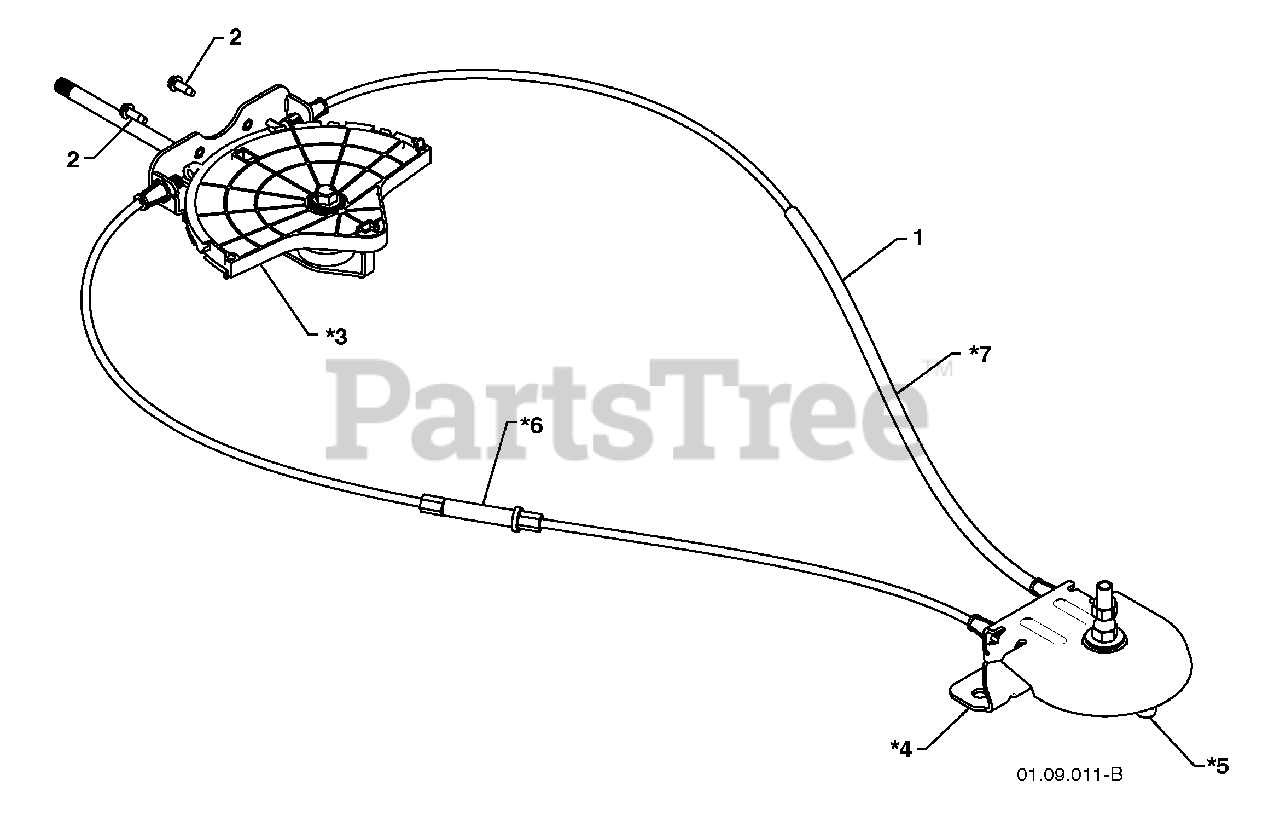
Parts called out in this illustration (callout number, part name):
1	LEVER/CABLE ROTATOR ASSEMBLY
2	SCREW 10-24 X .625
3	ROTATOR HEAD
4	ROTATOR PIVOT BRACKET
5	PULLEY PIVOT
6	CABLE ASSEMBLY ADJUSTABLE GRAY
7	CABLE ASSEMBLY HEAT SHIELD GRAY
